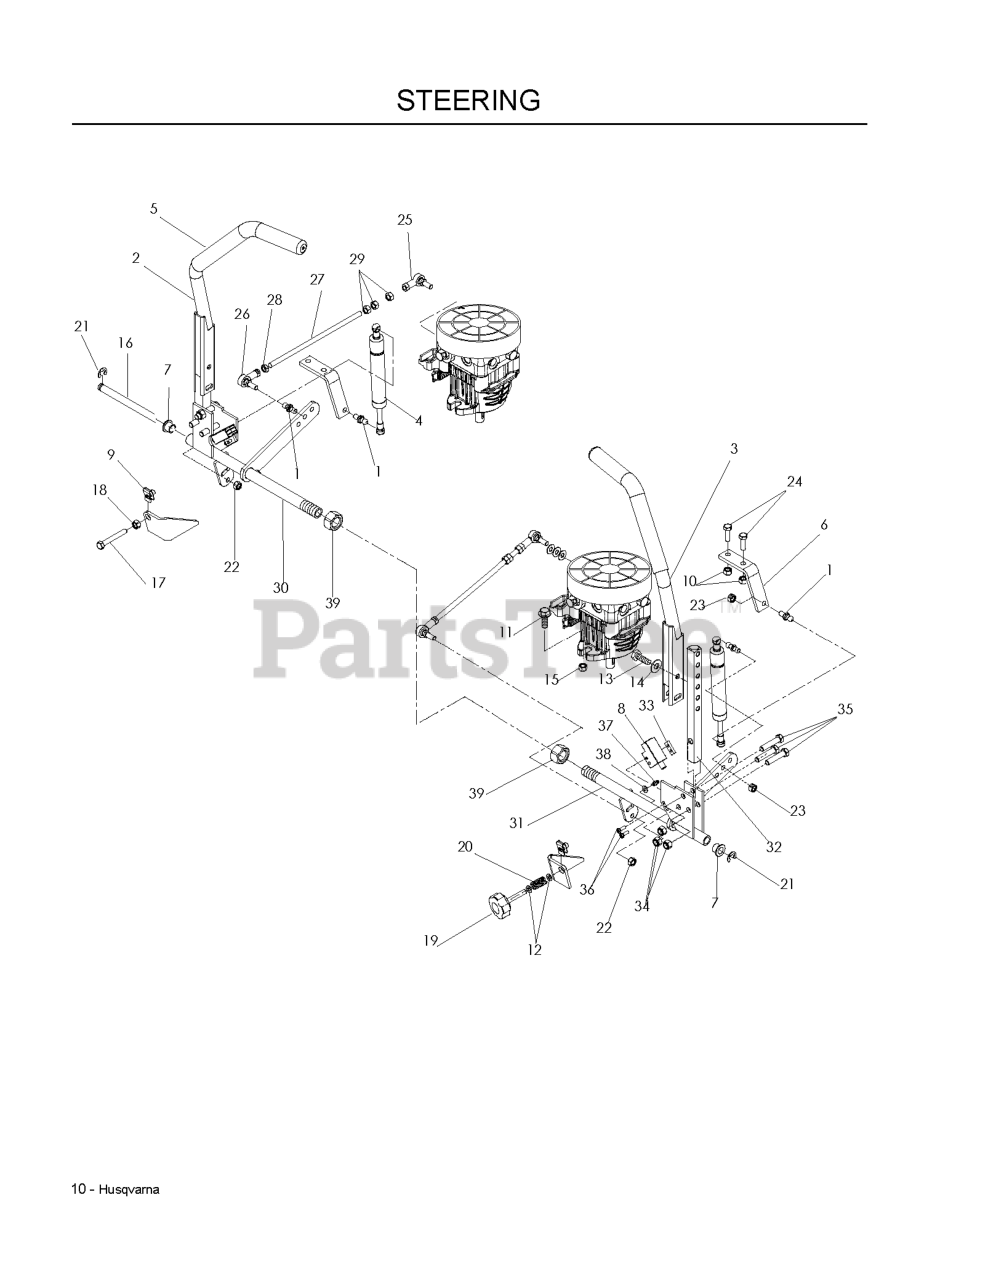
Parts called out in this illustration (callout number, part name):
1	STUD.BALL.10MM
2	ASSEMBLY, DRIVE LEVER RT
3	ASSEMBLY, DRIVE LEVER LT
4	DAMPENER W/EXT SEAL
5	GRIP - DRIVE LEVER 12"
6	DAMPENER BRACKET
8	SWITCH, INTERLOCK
9	U-CLIP 5/16-18 NUT RETAINER
10	NUT 5/16 NYLOC
11	4CS 3/8C X 1 SERRATED HEAD
12	WASHER 5/16 FLAT
13	HCS 3/8-16X1.GRD.5.ZD
14	WASHER, 3/8 DISC SPRING SPEC
15	NUT 3/8C CENTERBLOCK
16	CONTROL SHAFT
17	HCS 5/16-18X1-3/4 TPBLT
18	NUT 5/16C HEX
19	ADJUSTMENT KNOB
20	COMPRESSION SPRING
21	E-RING 1/2 (2 2)
22	NUT 5/16F NYLOC
23	NUT 5/16C CENTERLOCK
24	HCS 5/16C X 1
25	SPHERICAL ROD END, RH
26	SPHERICAL ROD END, LH
27	PUMP CONTROL LINK
28	NUT 5/16F LEFTHAND
30	CONTROL ASM - ADJ, RT
31	CONTROL ASM - ADJ, LT
32	CONTROL ARM
33	TAPPED PLATE
34	NUT 3/8-16 NYLOC
35	HCS 3/8-16 X 1 3/4 GR5
36	SCREW #10-24 X 5/8
37	ZERK
39	NUT 3/4 X 16 HEX CTR
